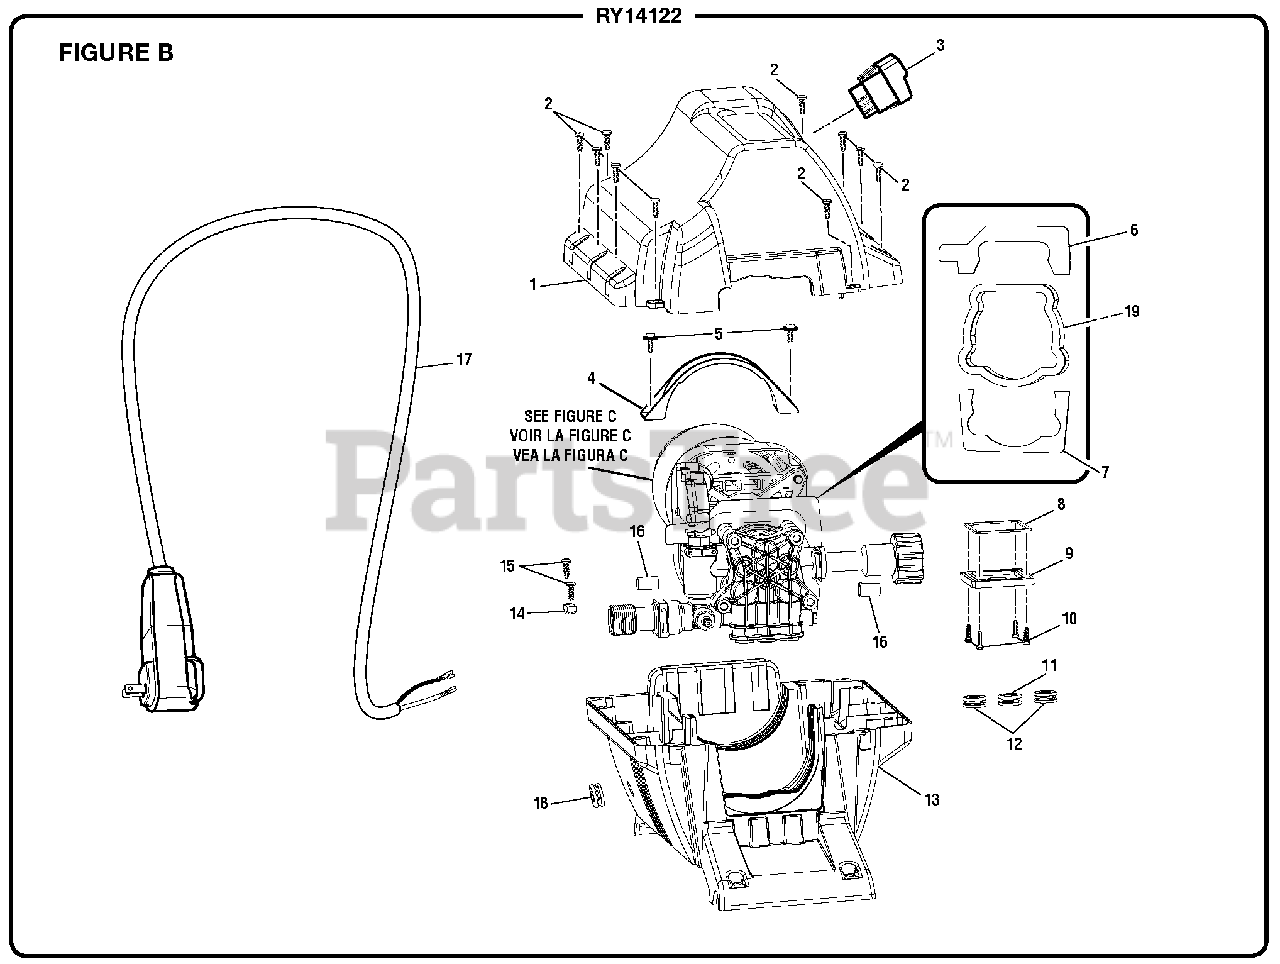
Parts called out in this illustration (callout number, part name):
1	Top Motor Housing
2	Screw (M4 x 15 mm)
4	Motor Bracket
5	Screw (M4 x 12 mm)
6	Upper Gasket
7	Lower Gasket
8	Switch Cover Gasket
9	Switch Cover
10	Screw (M3 x 14 mm)
13	Lower Motor Housing
14	Cord Clamp
15	Screw (M3.5 x 20 mm)
17	Power Cord
